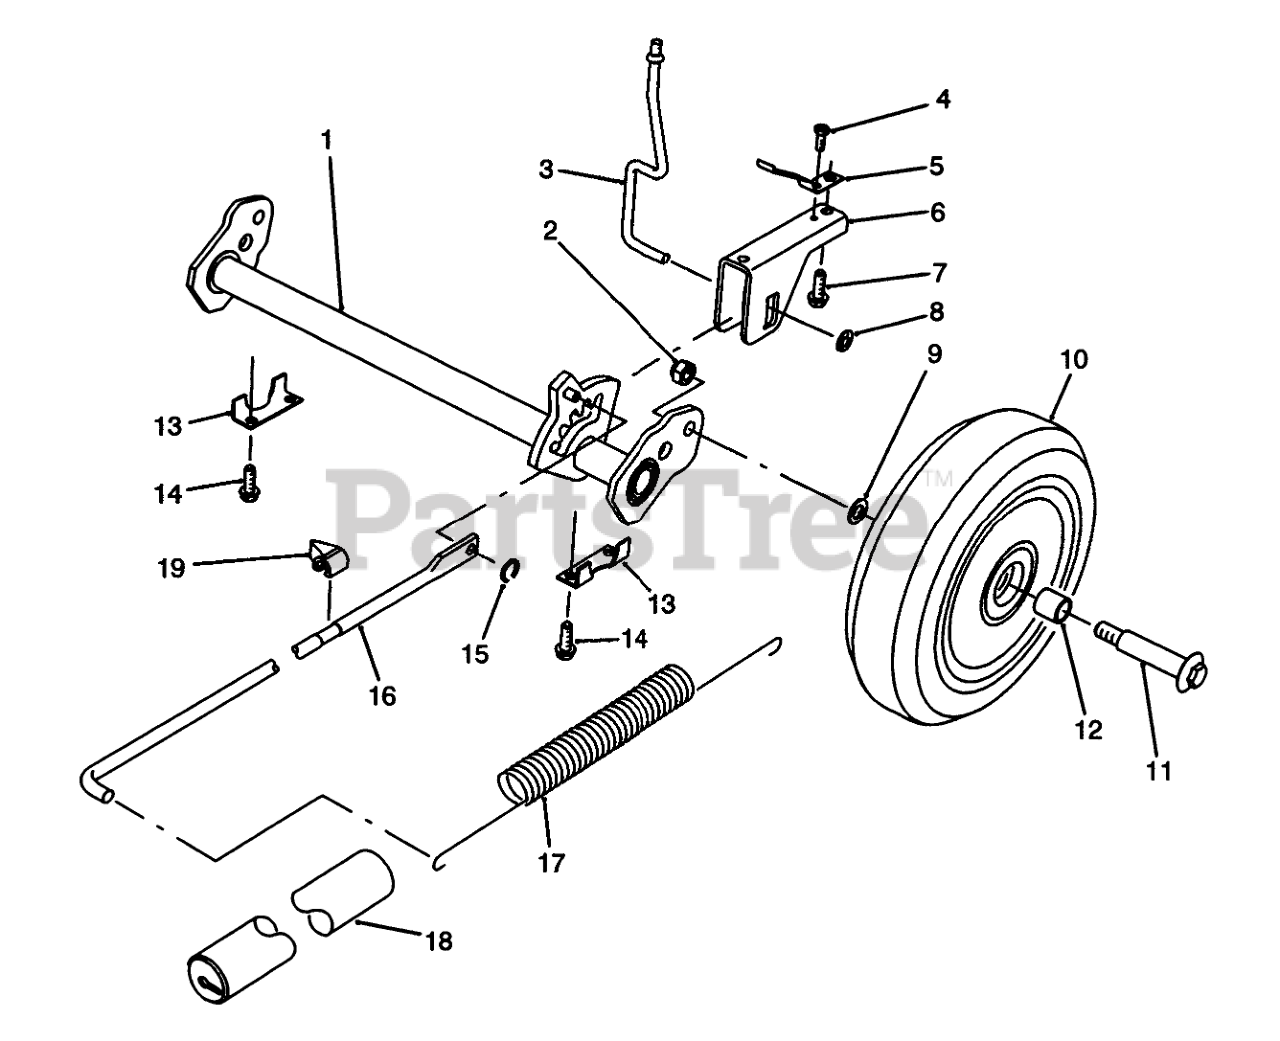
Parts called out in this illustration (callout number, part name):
1	PIVOT ARM REAR WA
2	NUT-HEX
3	TRIGGER ROD
4	SCREW 8 - 32 X 250
5	SPRING - TRIGGER RET
6	SADDLE - HOC
7	SCREW
8	PUSHNUT
9	WASHER
10	Wheel & Tire Assembly (Incl. Ref. #12)
11	BOLT-WHEEL
12	BUSHING
13	REAR SECURING PLATE
14	SCREW-HWH
15	GRIP RING
16	LINK ROD
17	SPRING-COUNTERBALANCE
18	COVER-SPRING
19	INDICATOR-HEIGHT OF CUT
